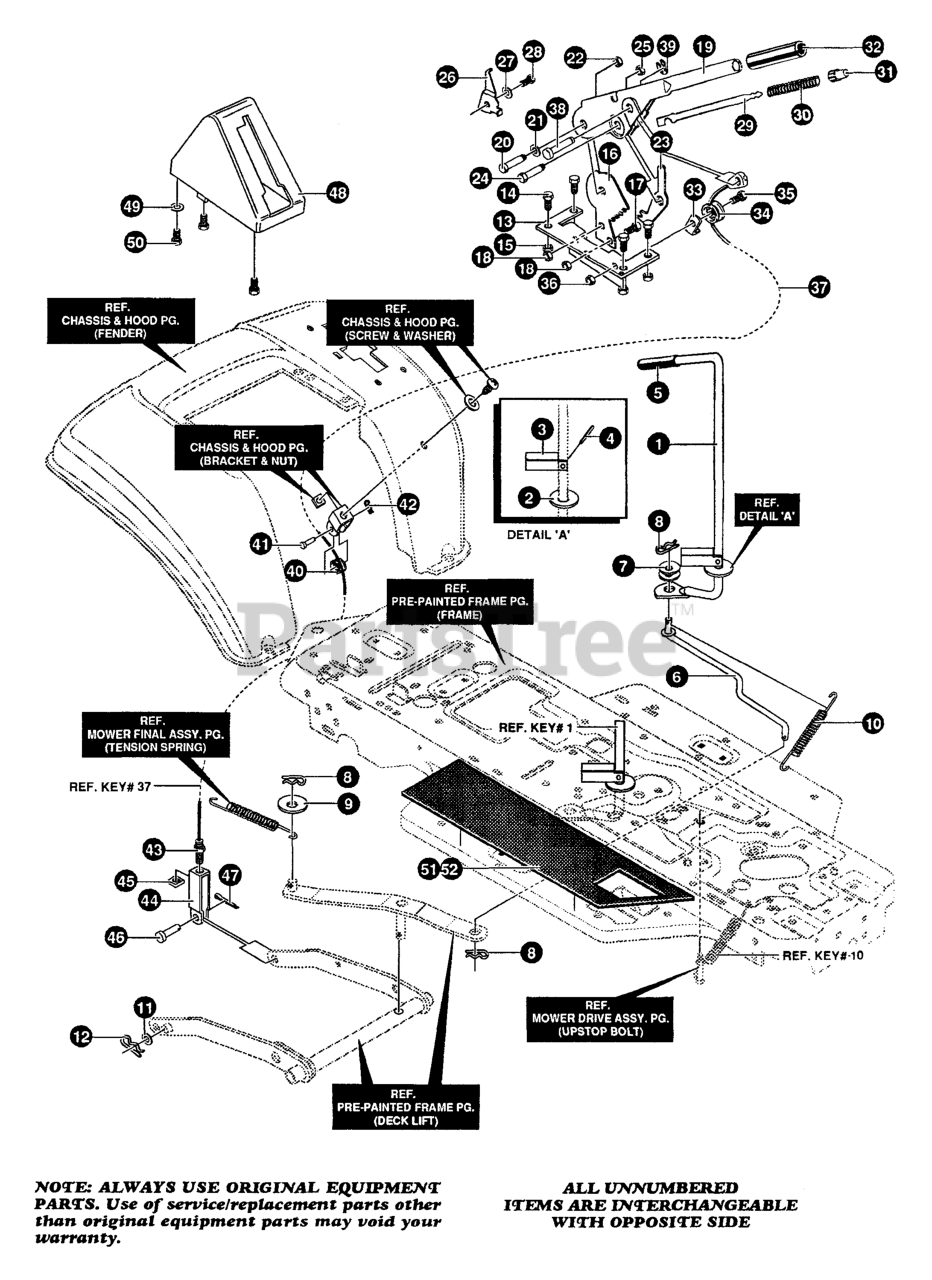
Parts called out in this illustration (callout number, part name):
1	LEVER, CLUTCH RH, PTO
2	WASHER, FLAT .515 X 1.38 X .119
3	STOP, PTO ENGAGE
4	PIN, SPRING
5	KNOB, ROUND 1.50 DIA
6	ROD, BELCRANK LINK
7	WASHER, FLAT .406 X .73 X .063
8	PIN, HAIR
9	WASHER, FLAT .386 X 1.25 X .09
10	SPRING, TENSION
11	WASHER, FLAT .531 X 1.06 X .063
12	PIN, HAIR
13	BRACKET, HEIGHT ADJUST
14	SCREW, 5/16-18 x 0.75
15	NUT, 5/16-18
16	QUADRANT, HEIGHT ADJUST
17	SCREW, 5/16-18 x 0.75
18	NUT, 5/16-18
19	HANDLE, LIFT
20	BOLT, .500 X .270
21	WASHER, FLAT .506 X .75 X .024
22	NUT, 5/16-18
23	PAWL, SQUARE
24	BOLT, .500 X .270
25	NUT, 5/16-18
26	POINTER, HEIGHT ADJUST
27	WASHER, .195 X .41 X .03
28	SCREW, #8-32 X .38
29	ROD, ACTUATOR-SHORT
30	SPRING, HEIGHT ADJUST
31	KNOB, HEIGHT ADJ PUSH BUTTON
32	GRIP BRACKET, CABLE RETAINER
35	BOLT, .375 X .375
36	NUT, 1/4-20
37	LIFT CABLE 20.75
38	PIN, CLEVIS
39	RING, RET E
41	PIN, CLEVIS
42	PIN, HAIR
43	NUT, 1/4-20
44	CLEVIS, LIFT CABLE
45	NUT, 1/4-20 REGSQ
46	PIN, CLEVIS
47	PIN, COTTER
48	LIFT COVER
49	WASHER, FLAT .281 X .63 X .065
50	SCREW, #10 X .75
51	FOOT PAD, RH, GRIT
52	FOOT PAD, LH, GRIT
